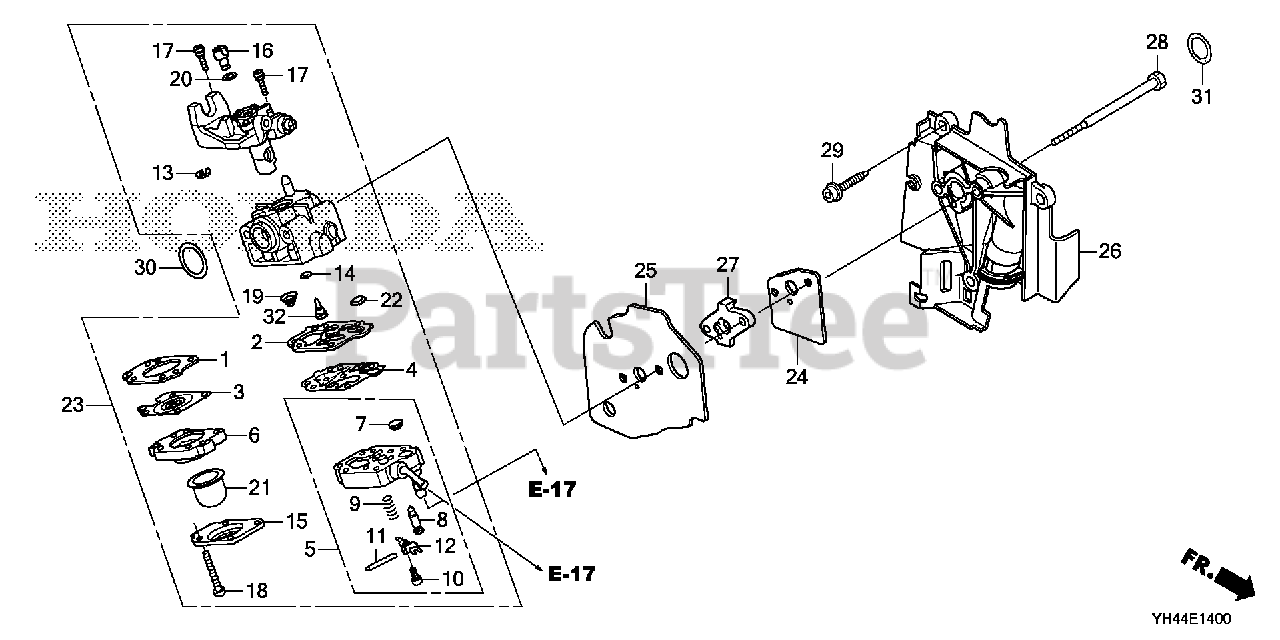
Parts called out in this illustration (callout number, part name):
1	GASKET, METERING DIAPHRAGM
2	GASKET, PUMP (CARBURETOR NO.)
3	DIAPHRAGM ASSY., METERING
4	DIAPHRAGM, PUMP
5	BODY ASSY., PUMP (CARBURETOR NO.)
6	BODY ASSY., AIR PURGE
7	SCREEN, INLET (CARBURETOR NO.)
8	VALVE, INLET NEEDLE
9	SPRING, METERING LEVER
10	SCREW, METERING LEVER PIN
11	PIN, METERING LEVER
12	LEVER, METERING
13	RING, RETAINING
15	COVER, PRIMER PUMP
17	SCREW, THROTTLE COLLAR
18	SCREW, PUMP COVER
19	SPRING, PUMP
21	PUMP, PRIMER
22	FILTER, FUEL INLET (CARBURETOR NO.)
23	CARBURETOR ASSY. (WYB 35A/B)
24	GASKET, CARBURETOR
25	GASKET, SHROUD
26	SHROUD
27	SPACER, SHROUD
28	BOLT (5X58)
29	BOLT, SOCKET (5X16)
30	O-RING (14.8X2.4)
31	O-RING (12.3X2.4) (CARBURETOR NO.)
32	JET (#33) (CARBURETOR NO.)
32	JET (#34) (CARBURETOR NO.)
32	JET (#32) (CARBURETOR NO.)
